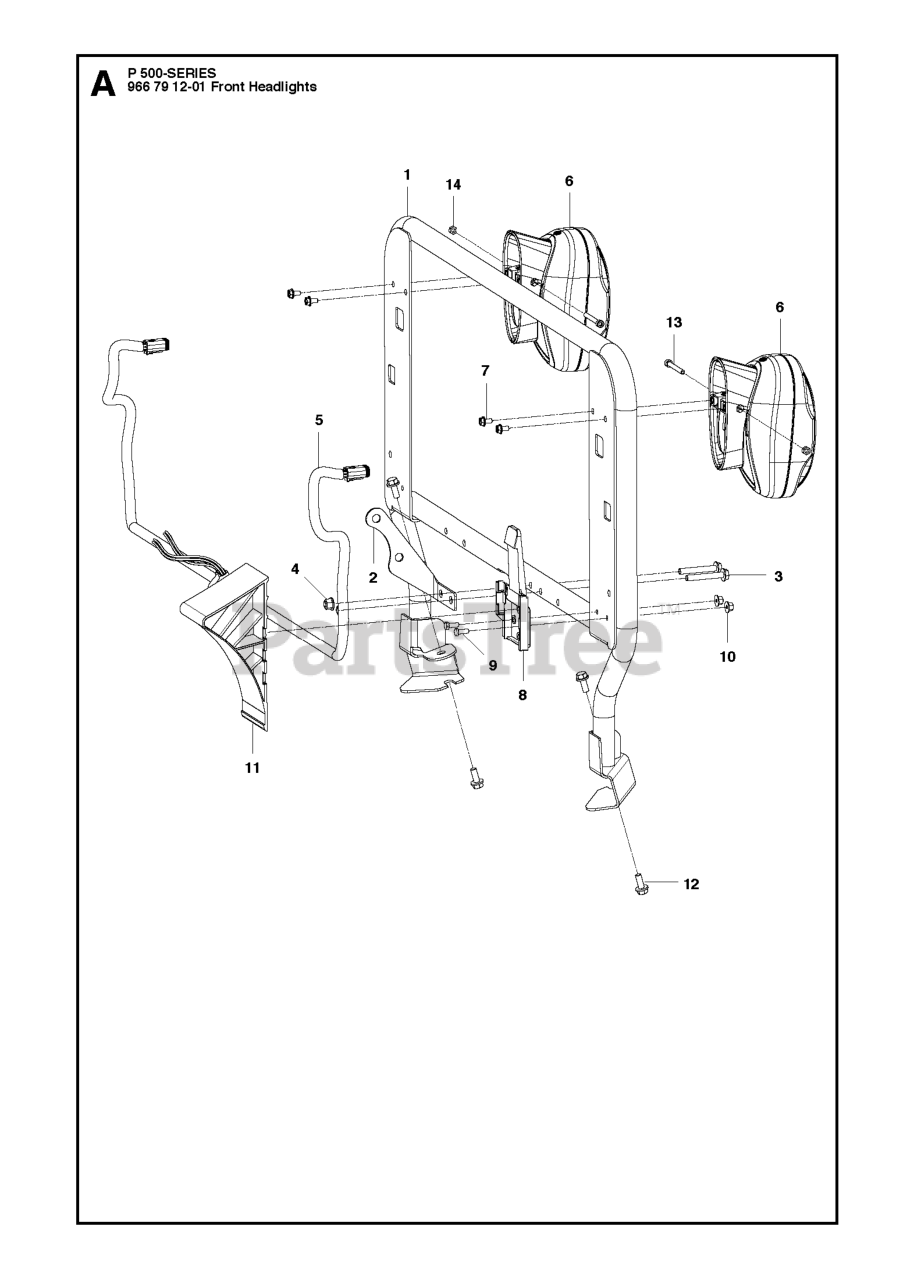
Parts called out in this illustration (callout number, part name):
3	SCREW EHHFM
4	NUT FLANGE
7	SCREW EHHFM
9	BOLT FLANGE - M6X20
10	NUT FLANGE
12	BOLT
14	NUT
